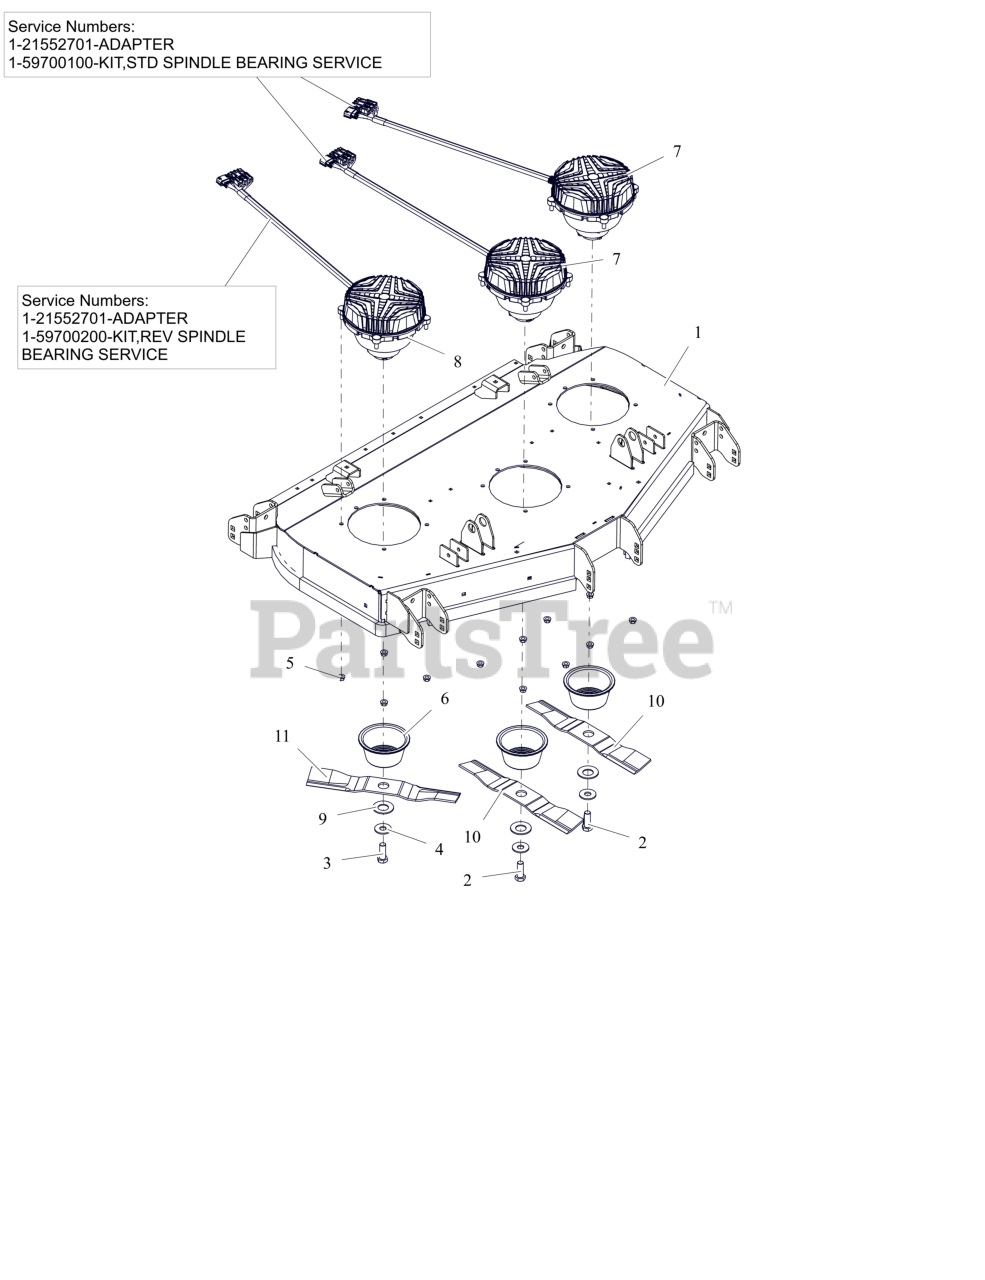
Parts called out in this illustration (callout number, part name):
1	KIT,DECK 48 RD W/DECALS-G
2	BLT, HEX .62-18X1.75 G8 ZCC
3	BLT, HEX 0.625-11X1.75 GR8 ZCC LH
4	WSHR, HRDN 0.687X1.75X0.134 HRD
5	NUT-LK-CTR-FLG .375-16 GF ZCC
6	GUARD, SPINDLE LOWER
7	MOTOR, DECK - 48"/52" CW
7	ADAPTER
7	KIT, STD SPINDLE BEARING SERVICE
8	MOTOR, DECK - 48"/52" CCW
8	ADAPTER
8	KIT,REV SPINDLE BEARING SERVICE
9	WSHR, BLVL - .56X28.5X3 PHOS.COAT
10	BLADE, MOWER -16.190" EFF CW
11	BLADE, MOWER -16.190" EFF CCW
